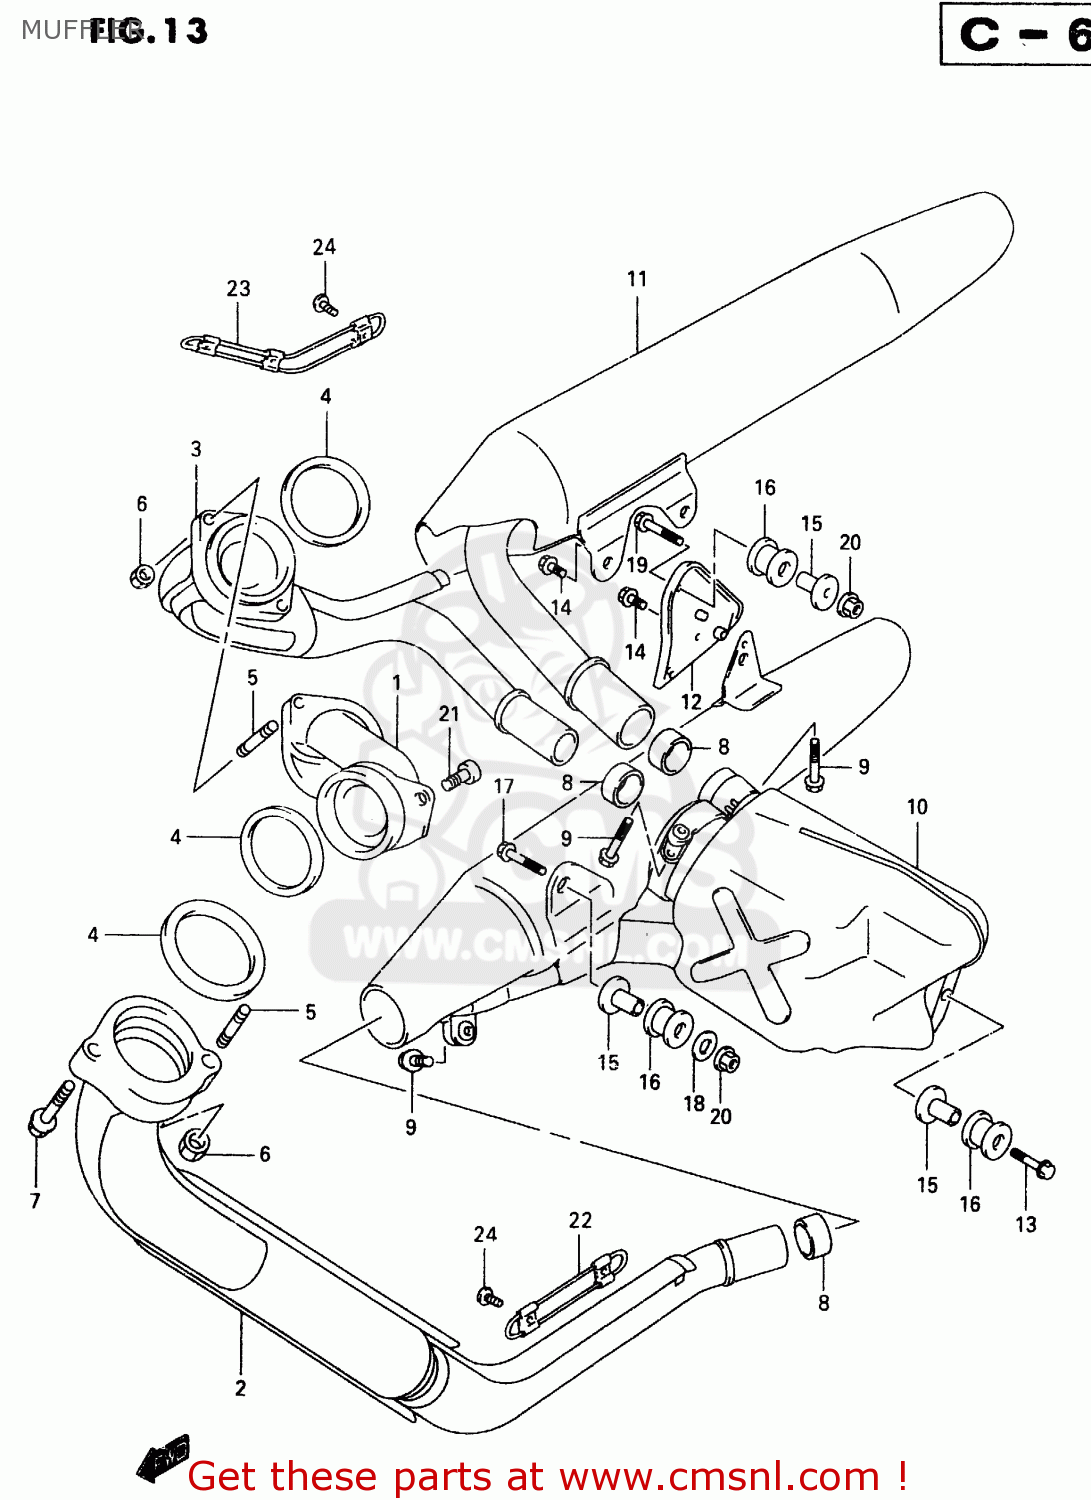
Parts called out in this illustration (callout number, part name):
1	MANIFOLD,EXHAUST,REAR
2	PIPE COMP,EXHAUST,RIGHT
3	PIPE,EXHAUST,L
4	GASKET,EXHAUST PIPE (NAS)
5	BOLT,STUD
6	NUT
7	BOLT(8X35)
8	CONNECTOR,MUFFLER JOINT
9	BOLT(8X33)
10	MUFFLER, RH
11	BODY COMP,MUF,
12	BRACKET,MUFFLER SUPPORT
13	BOLT 8X45
14	BOLT(8X14)
15	SPACER(8.6X12X27.1)
16	CUSHION
17	BOLT
18	WASHER (8.5X33X1.6)
19	BOLT
20	NUT
21	BOLT
22	GUARD,EXHAUST,RIGHT
23	GUARD,EXHAUST,LEFT
24	SCREW(6X10)
